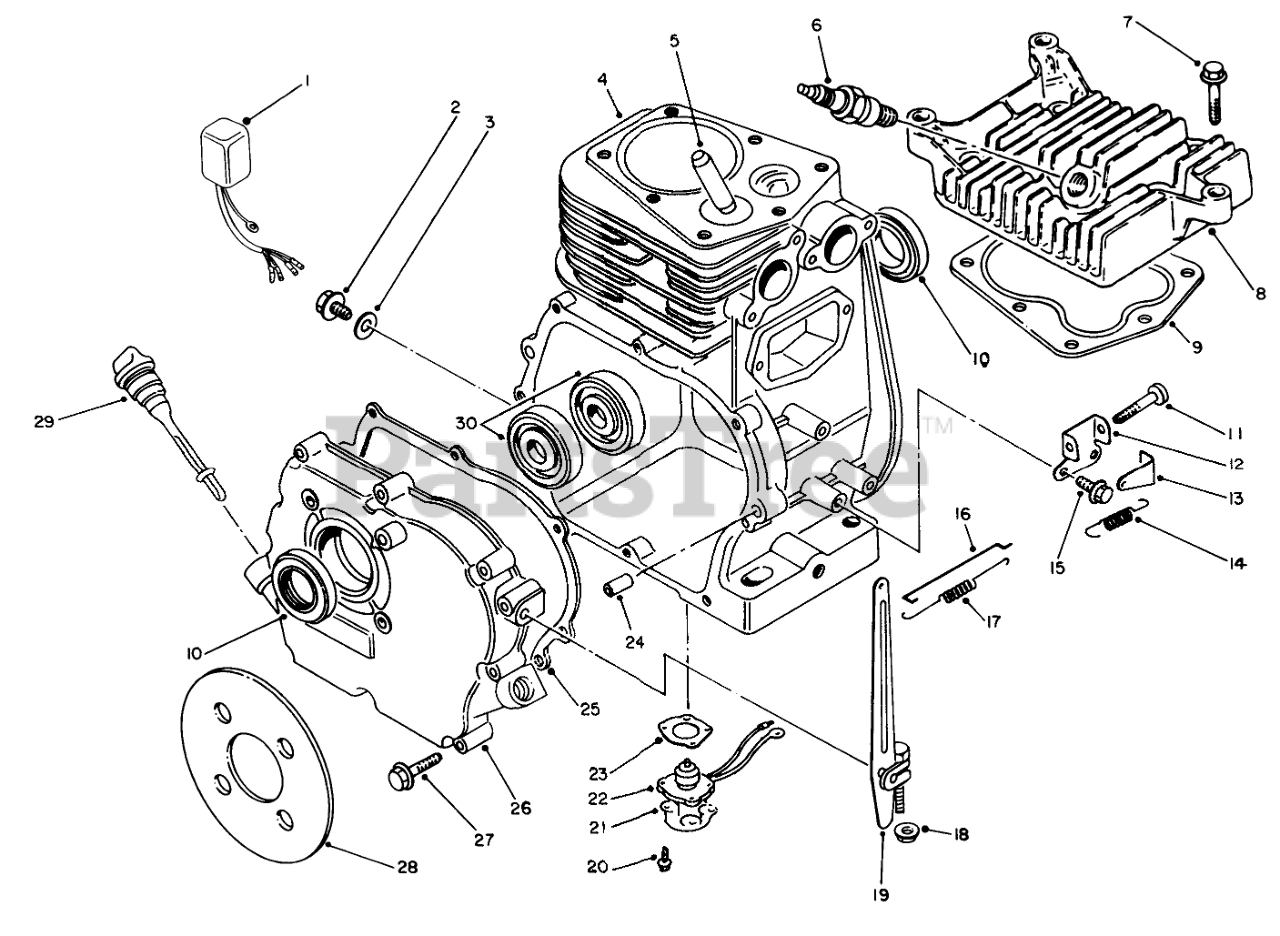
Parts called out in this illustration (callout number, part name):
1	OIL LEVEL UNIT
2	Drain Plug
3	GASKET
4	Cylinder
5	VALVE GUIDE
6	SPARK PLUG
8	Cylinder Head
9	GASKET
10	Oil Seal
12	Bracket
14	SPRING
16	Rod-Carburetor
17	SPRING
19	Lever-Control
21	Plate
22	SENSOR
23	GASKET
25	Gasket-Crankcase
26	Cover-Crankcase Side
28	Seat-Joint
29	Gauge-Oil Level
30	Bearing
